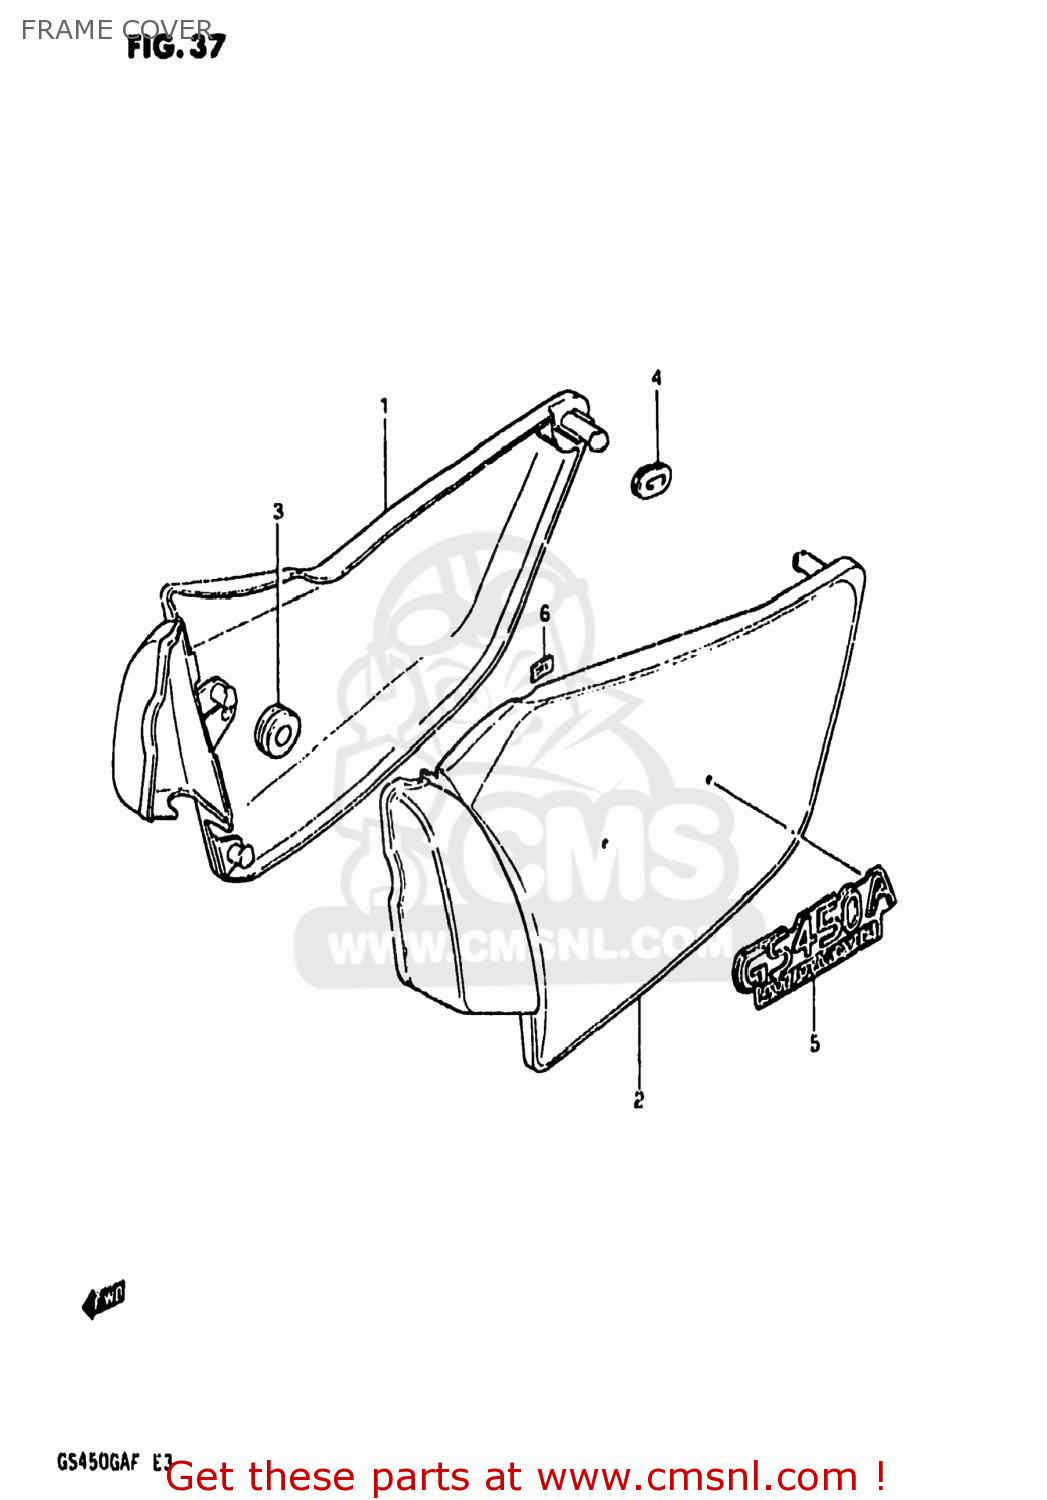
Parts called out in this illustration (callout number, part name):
1	COVER,FRAME,RIGHT
2	COVER,FRAME,LEFT
3	CUSHION
4	CUSHION
5	EMBLEM,FRAME COVER
6	NUT
